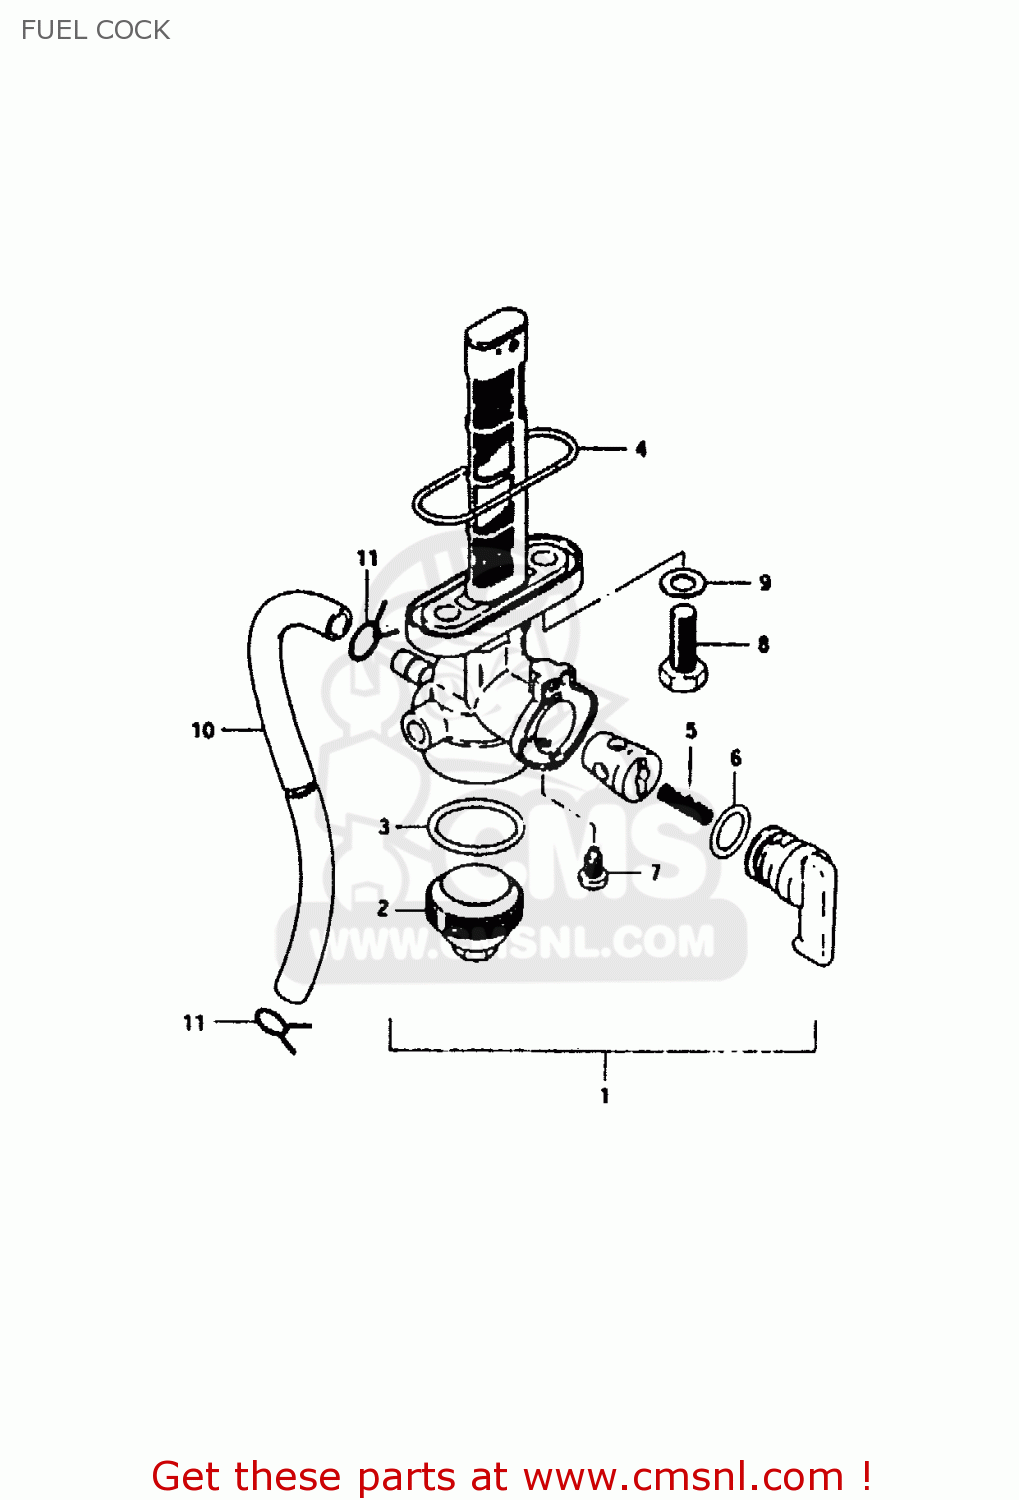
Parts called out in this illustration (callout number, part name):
1	COCK ASSEMBLY,FUEL
2	CUP,STRAINER
3	GASKET,FILTER (NAS)
4	O RING,FUEL COCK
5	SPRING
6	O-RING
7	SCREW
8	BOLT(6X20)
9	GASKET
10	HOSE
11	CLIP
